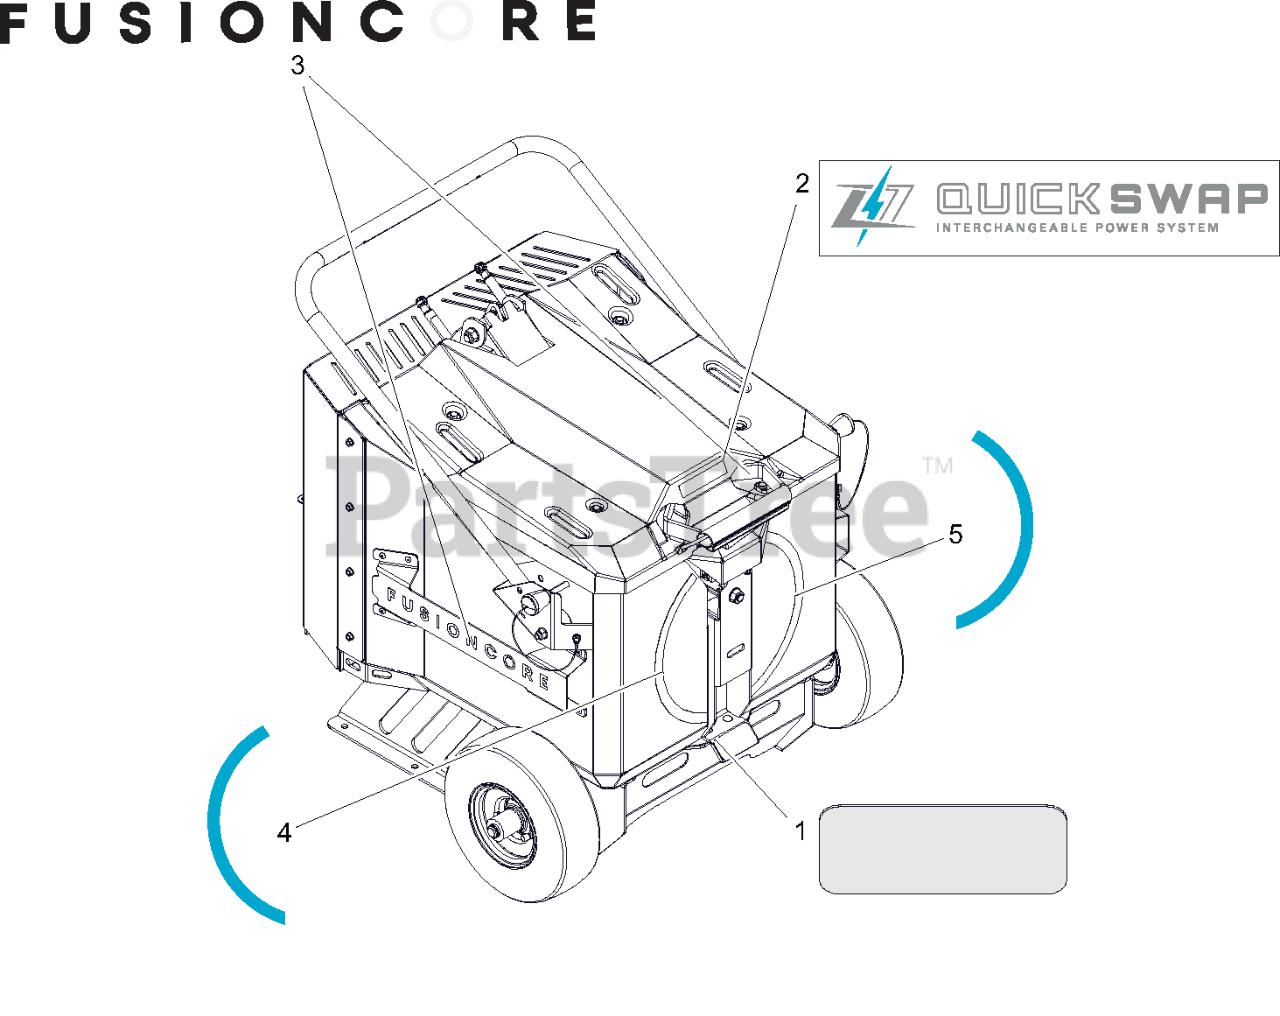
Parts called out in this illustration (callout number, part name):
1	GRIP, PEDAL 1.50 X 3.00
2	DECAL, QUICK SWAP - HATCH
3	DECAL, FUSIONCORE
4	DECAL, FUSION -LH
5	DECAL, FUSION -RH
